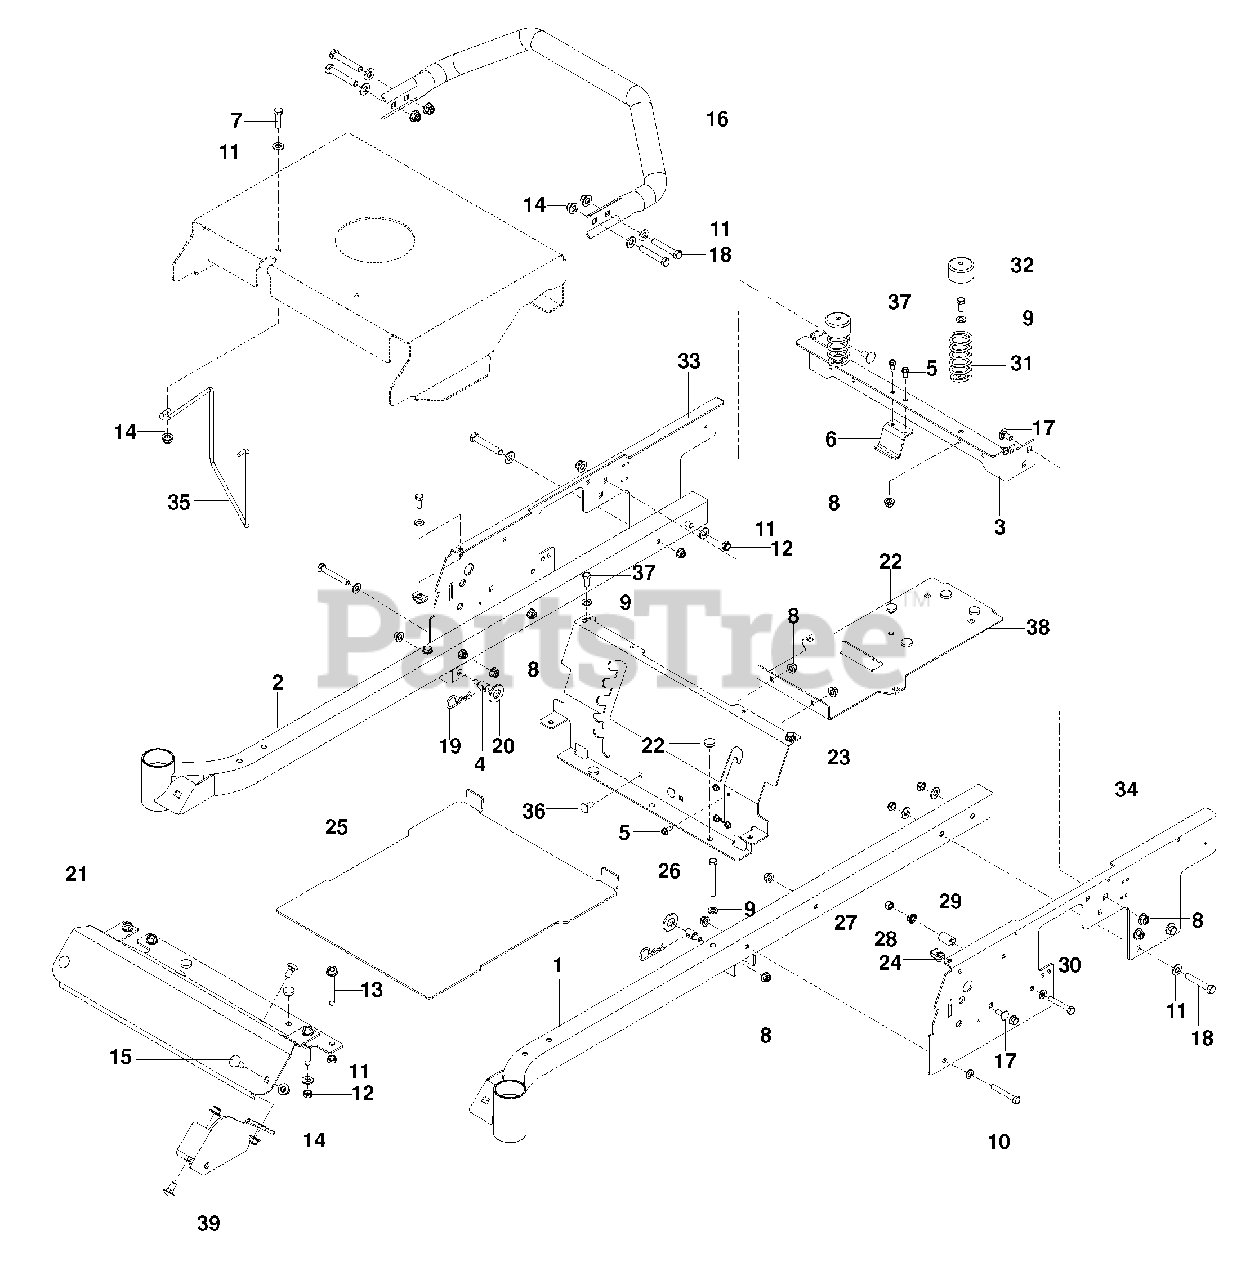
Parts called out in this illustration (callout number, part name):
1	FRAME TUBE, LH
2	FRAME TUBE, RH
3	SEAT SUPPORT, REAR
4	STUD w/ ANTI-ROTATE
5	SCREW 1/4-20 x 5/8 SLF TAP
6	BRACKET, FUEL TANK
7	HCS 3/8-16 x 1 1/4
8	NUT 5/16-18 FLANGE NYLOC
9	WASHER 5/16 SAE FLAT
10	HCS 5/16-18 x 2 1/4
11	WASHER 3/8 SAE FLT
12	NUT 3/8-16 HEX JAM NYLOC
13	BOLT 3/8-16 x 25/8 THD FRM
14	NUT 3/8-16 FLANGE NYLOC
15	RHSNB 3/8-16 x 1
16	GUARD, REAR
17	RHSNB 3/8-16 x 3/4
18	HCS 3/8-16 x 2 1/4
20	WASHER 5/8 SAE FLT
22	GROMMET, BUMPER
23	PANEL, SEAT SUPPORT
24	RETAINER, U TYPE
25	FOOT PLATE
26	HCS 5/16-18 x 2 3/4
27	NUT 5/16-18 HEX WHIZLK
29	NUT 5/16-18 HEX NYLOC
30	HCS 5/16-18 x 2
31	SPRING, SEAT
32	CAP, SPRING
35	GUIDE, BELT
36	RHSNB 5/16-18 x 3/4
37	HCS 5/16-18 x 3/4
38	SUPPORT, TANK
39	BRACKET, FRONT DECK
